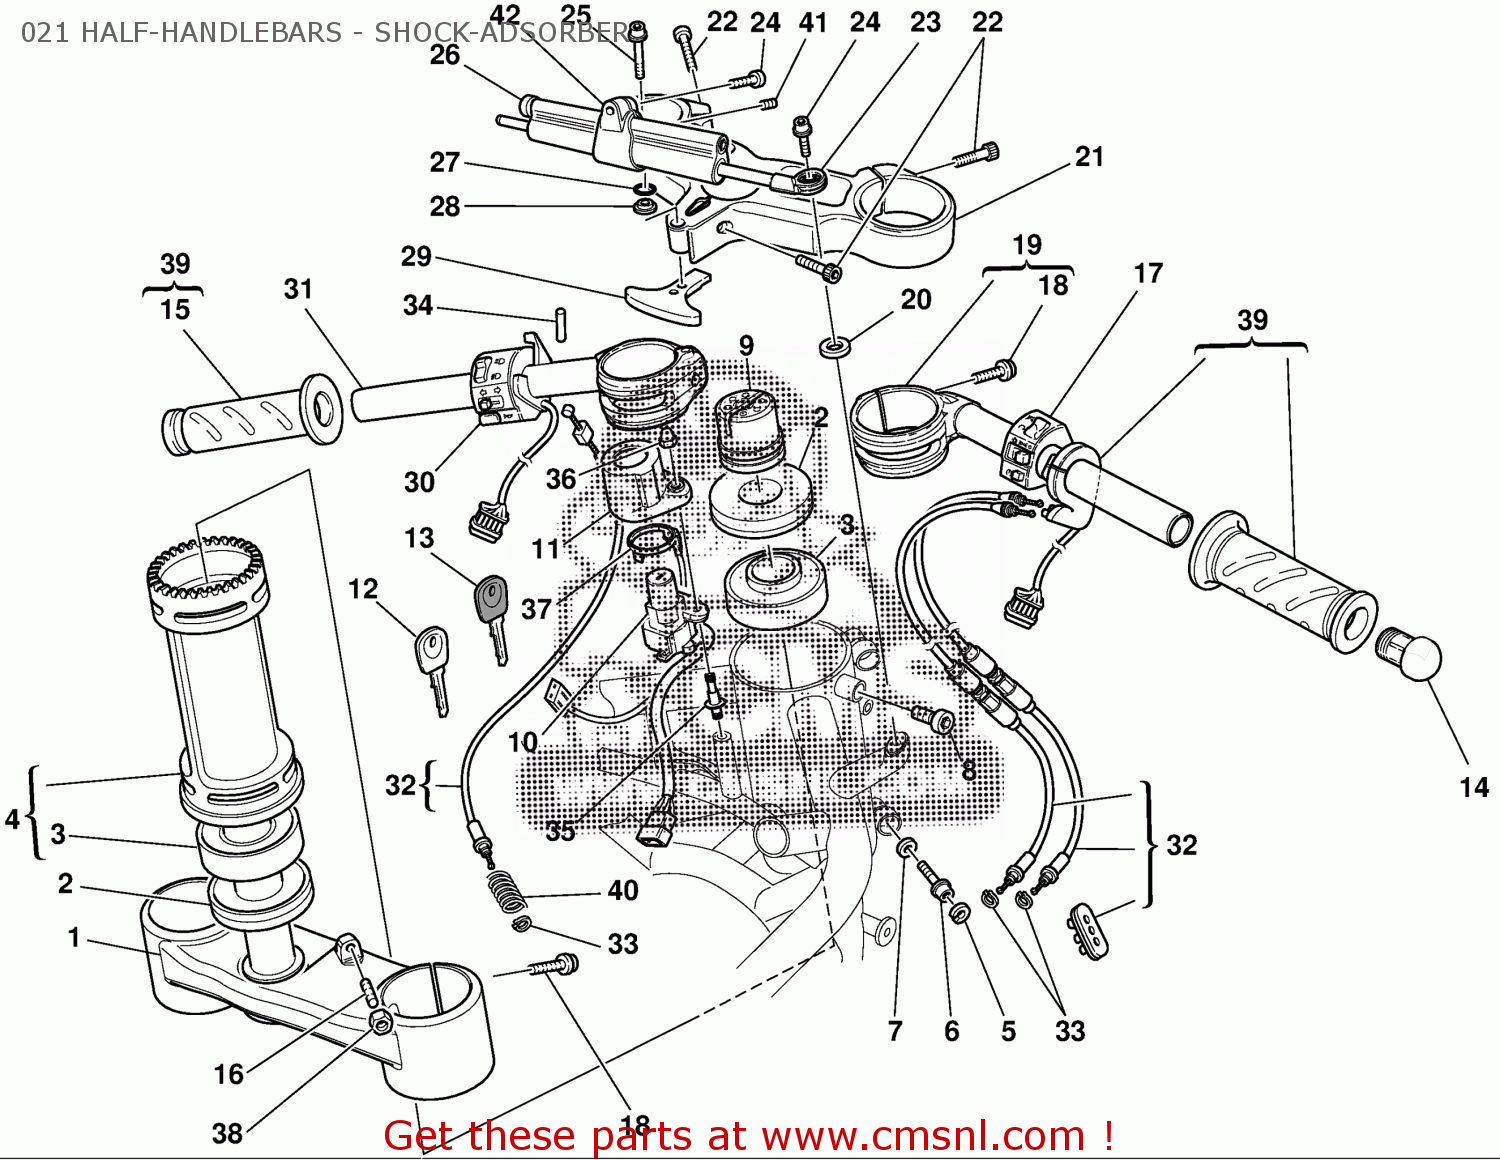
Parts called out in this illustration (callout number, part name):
1	STEERING CROWN WITH PIN
2	OIL SEAL
3	BEARING, CONICAL ROLLERS
4	TUBE
5	CIRCLIP
6	SCREW TCEIF M8X20
7	THRUST WASHER 1 MM
8	SCREW, SPECIAL
9	THREAD, STEERING HEAD TOP
10	KEY-OPERATED SWITCH
11	COVER, IGNITION SWITCH
12	KEY, BLANK W/TRANSMITTER
13	KEY BLANK
14	BALANCER SET, HANDLE BAR
15	HAND GRIP LH
16	SCREW, SPECIAL
17	RIGHT HANDLE SWITCH
18	SCREW TCEIF M8X25
19	RIGHT HALF-HANDLEBAR
20	SPACER
21	STEERING HEAD
22	SCREW TCEIF M8X30
23	BALL JOINT, STEERING DAMPER
24	SCREW TCEIF M6X18
25	SCREW TCEIF M6X40
26	STEERING DAMPER
27	O-RING
28	SPACER
29	STEERING LOCK ARM
30	LEFT HANDLE SWITCH
31	LEFT HALF-HANDLEBAR
32	CABLE, THROTTLE & STARTER
33	SPRING RING
34	PIN, SPRING 4X12
35	SCREW, SPECIAL
36	NUT, SELF-LOCKING M6
37	ANTENNA IMMOBILIZER
38	NUT 6MM
39	THROTTLE CONTROL
40	SPRING, STARTER CABLE
41	THREADED DOWEL M4X6
42	CLAMP
